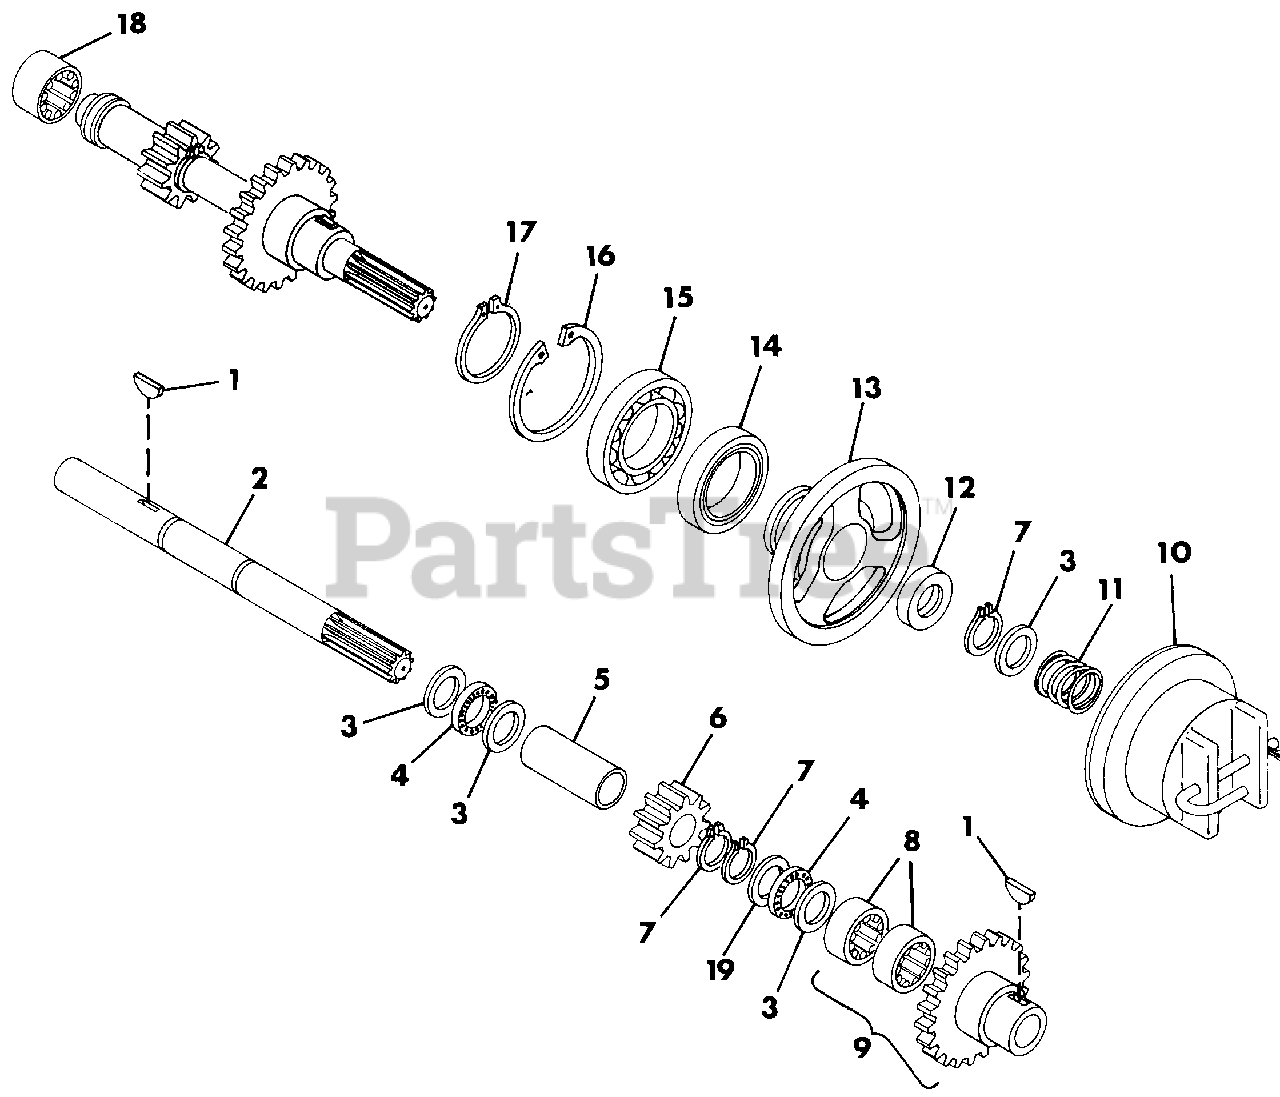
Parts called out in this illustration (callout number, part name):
1	KEY, WOODRUFF .187X.625 HARD #61
2	SHAFT, SPLINED REVERSE CLUTCH
3	RACE, BEARING THRUST .752X1.240X.03
4	BEARING, NEEDLE THRUST
5	SPACER, #2 SHAFT
6	GEAR, 10 DP 16 TEETH X.750
7	RING, RETAINING .750 SHAFT
8	BEARING, NEEDLE .750X1.000X.500
9	ASM, REVERSE GEAR AND BEARING
10	NUMBER 11 - FWD-REV CLUTCH ASM.
11	SPRING, COMP. TYPE 1.0X.80X36 16/IN.
12	SEAL, OIL .750X1.625X.250
13	HUB, CLUTCH
14	SEAL, OIL 2.250X3.005X.375
15	BEARING, BALL 1.968X3.149X.629
16	RING, RETAINING 3.156 BORE
17	RING, RETAINING 1.969 SHAFT
18	BEARING, NEEDLE .75X1.00X.75
19	RACE, BEARING THRUST .060
